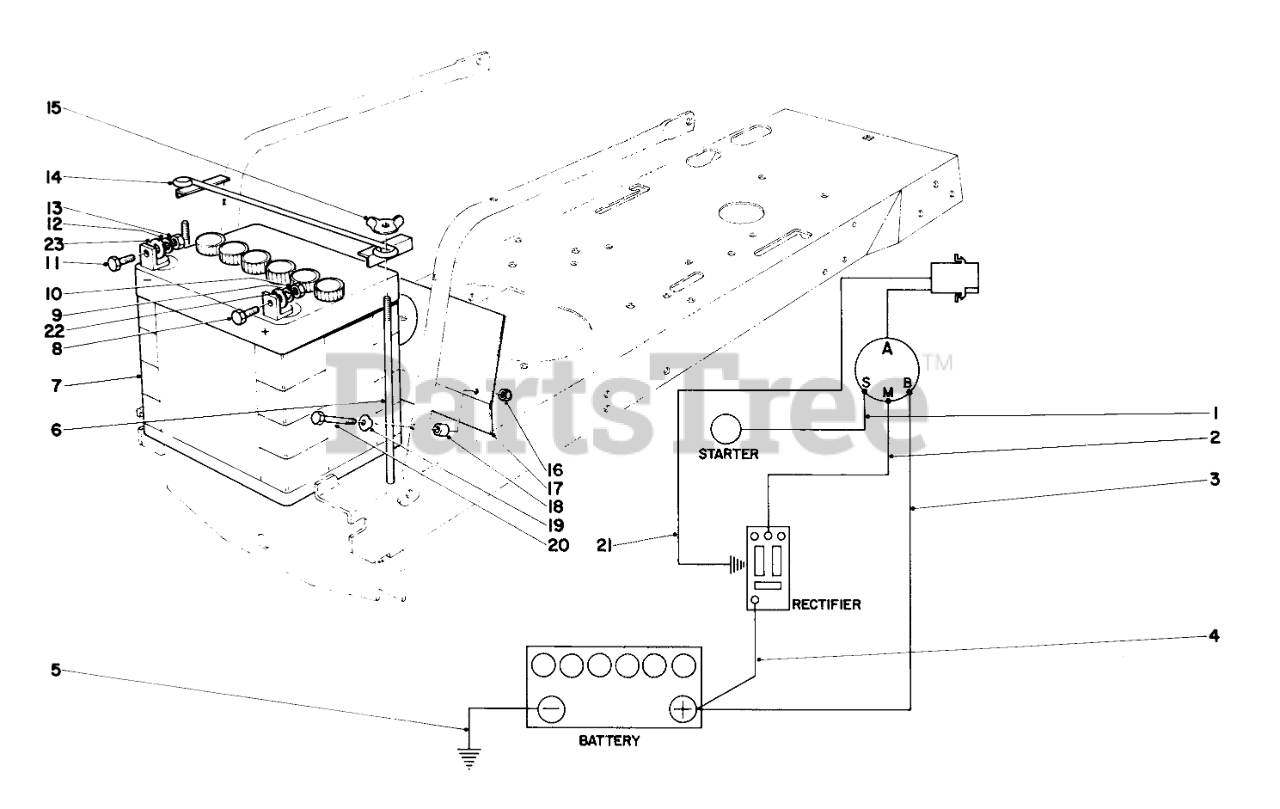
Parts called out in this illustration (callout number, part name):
1	Wire Assy. Switch to Starter
2	Wire Switch to Mag.
4	Wire Assy. Battery to Engine
5	Wire Assembly
6	BATTERY BOLT
7	Battery
8	SCREW-HH
9	WASHER-LOCK/SP
10	NUT-HEX
11	SCREW-HH
12	WASHER-LOCK
13	NUT-HEX
14	Clamp
15	NUT-WING
17	Heat Shield
18	GRILLE HINGE SPACER
19	WASHER
20	SCREW-HH
21	Wire Assembly
22	WASHER-FLAT
23	WASHER-FLAT
